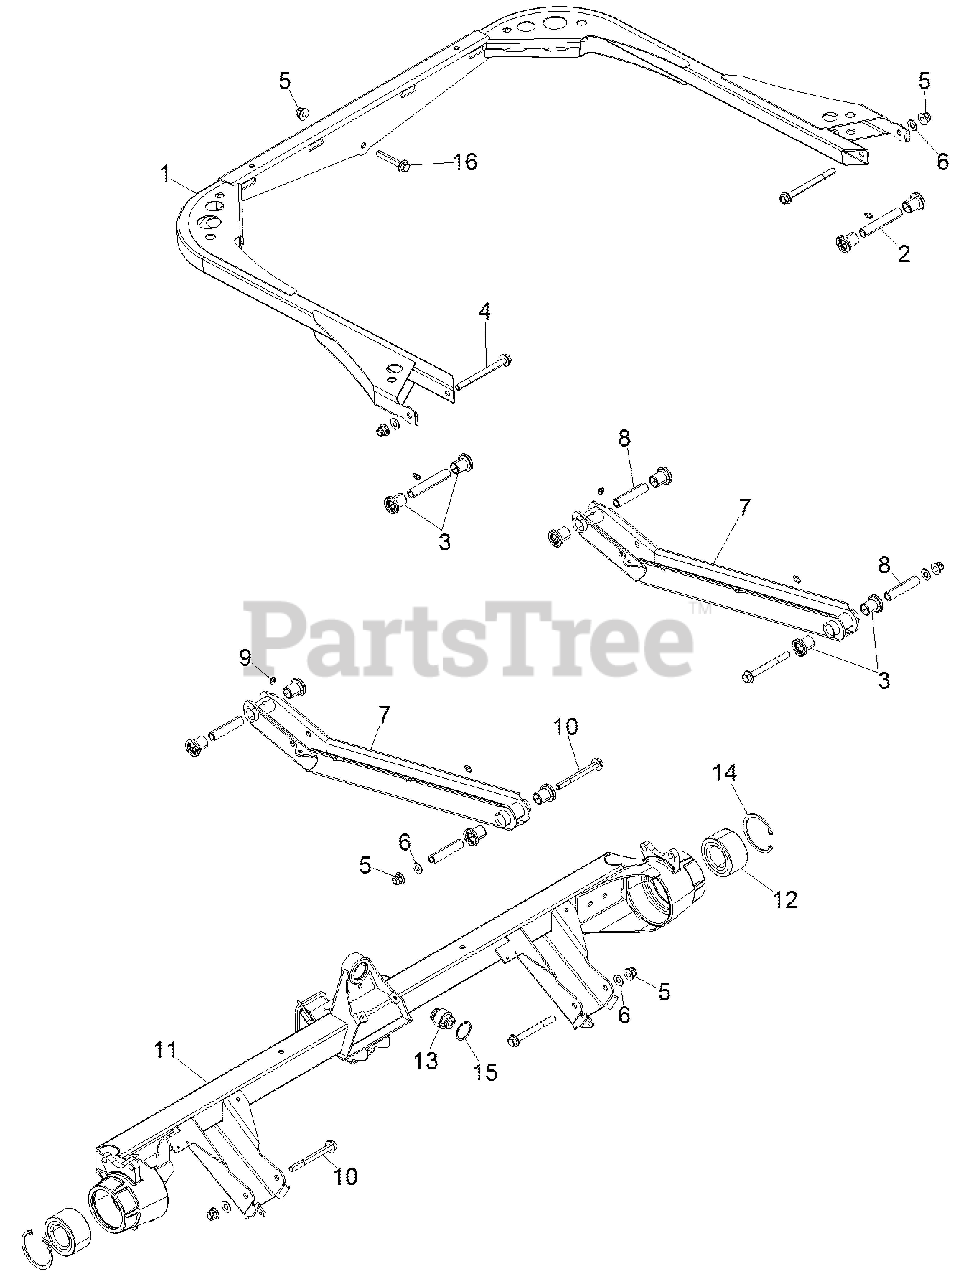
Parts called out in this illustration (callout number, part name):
1	WELD-UPPER LINK,M.BLK
2	SHAFT-PIVOT,89.71MM,15.88OD
3	BUSHING-STANDARD,ORV
4	BOLT-M10X1.25X115,HXFLG-OLIVED
5	NUT-M10X1.25,FLG,NYLOC-OLIVE D
6	WASHER,3/8 FW
7	WELD-LOWER LINK,M.BLK
8	SHAFT-PIVOT,70.99MM,15.88OD
9	FITTING, LUBRICATION
10	SCR-HXFL-M10X1.25X95 10.9 ZOD
11	AXLE, REAR BRACE, MATTE BLACK
12	BEARING, WHEEL
13	BEARING-SPHERICAL LOWER 10MM
14	RING,RETAINING
15	RING-RETAINING,1.25 ID HSNG
16	SCR-HXFL-M10X1.5 X 65 10.9 RIE
